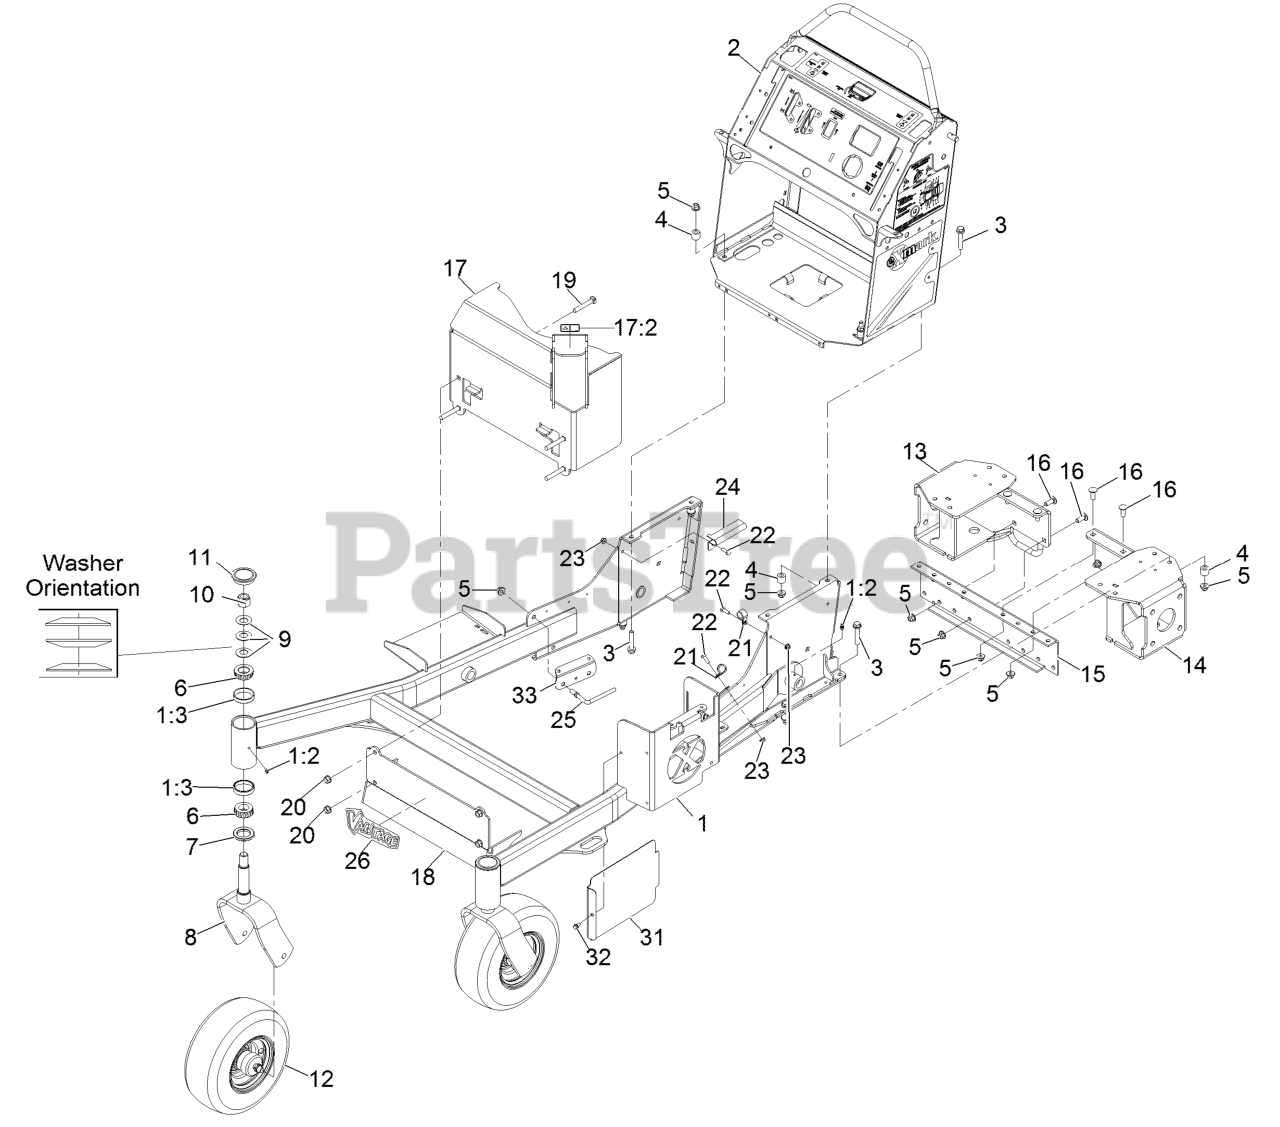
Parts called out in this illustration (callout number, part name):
1	FRONT FRAME ASM
1:2	FITTING-GREASE
2	CONTROL TOWER ASM
3	SCREW-HHF
5	NUT-HF, NI
6	Cone-Bearing Tapered Roller
7	SEAL-GREASE
8	FORK-CASTER
9	WASHER-BELLVILLE
10	NUT-LOCK, NI
11	CAP-GREASE
12	WHEEL/TIRE AND BEARING AS
13	RH MOTOR MOUNT ASM
14	LH MOTOR MOUNT ASM
15	MOUNT-MOTOR, CENTER
16	SCREW-CARR
17	MUFFLER GUARD ASM
17:2	DECAL-WARNING
18	PANEL-GUARD
19	SCREW-CARR
21	CLAMP-CABLE
22	SCREW-HH
24	BRACKET-HOSE, FUEL (DOUBL
25	GUIDE-HOSE, SUPPORT
26	DECAL-VANTAGE LOGO
31	SHIELD-HEAT, TALL
32	SCREW-HWH
33	GUARD-HOSE
